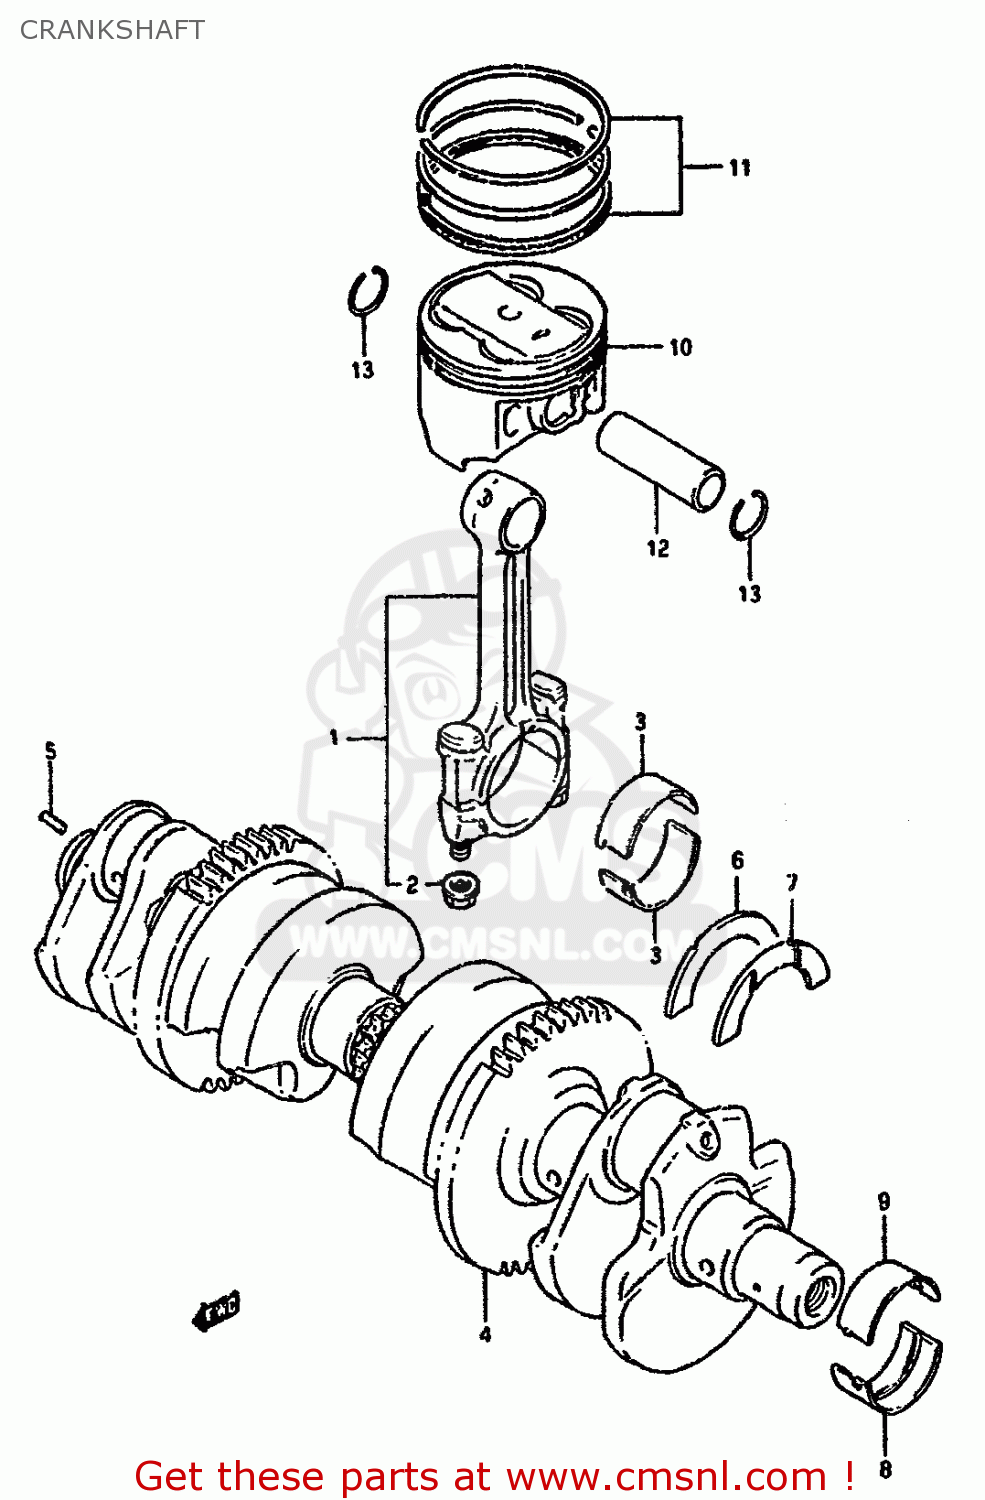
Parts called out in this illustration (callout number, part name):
1	ROD ASSEMBLY,CONNECTING
2	NUT
3	BEARING,CRANK PIN
4	CRANKSHAFT SET
5	PIN
6	BEARING,CRANK THRUST(GREEN)
7	BEARING,CRANK THRUST(RED)
8	BEARING,CRANKSHAFT LWR
9	BEARING,CRANKSHAFT UPR
10	PISTON
11	RING SET,PISTON
12	PIN,PISTON
13	CIRCLIP,PISTON PIN
